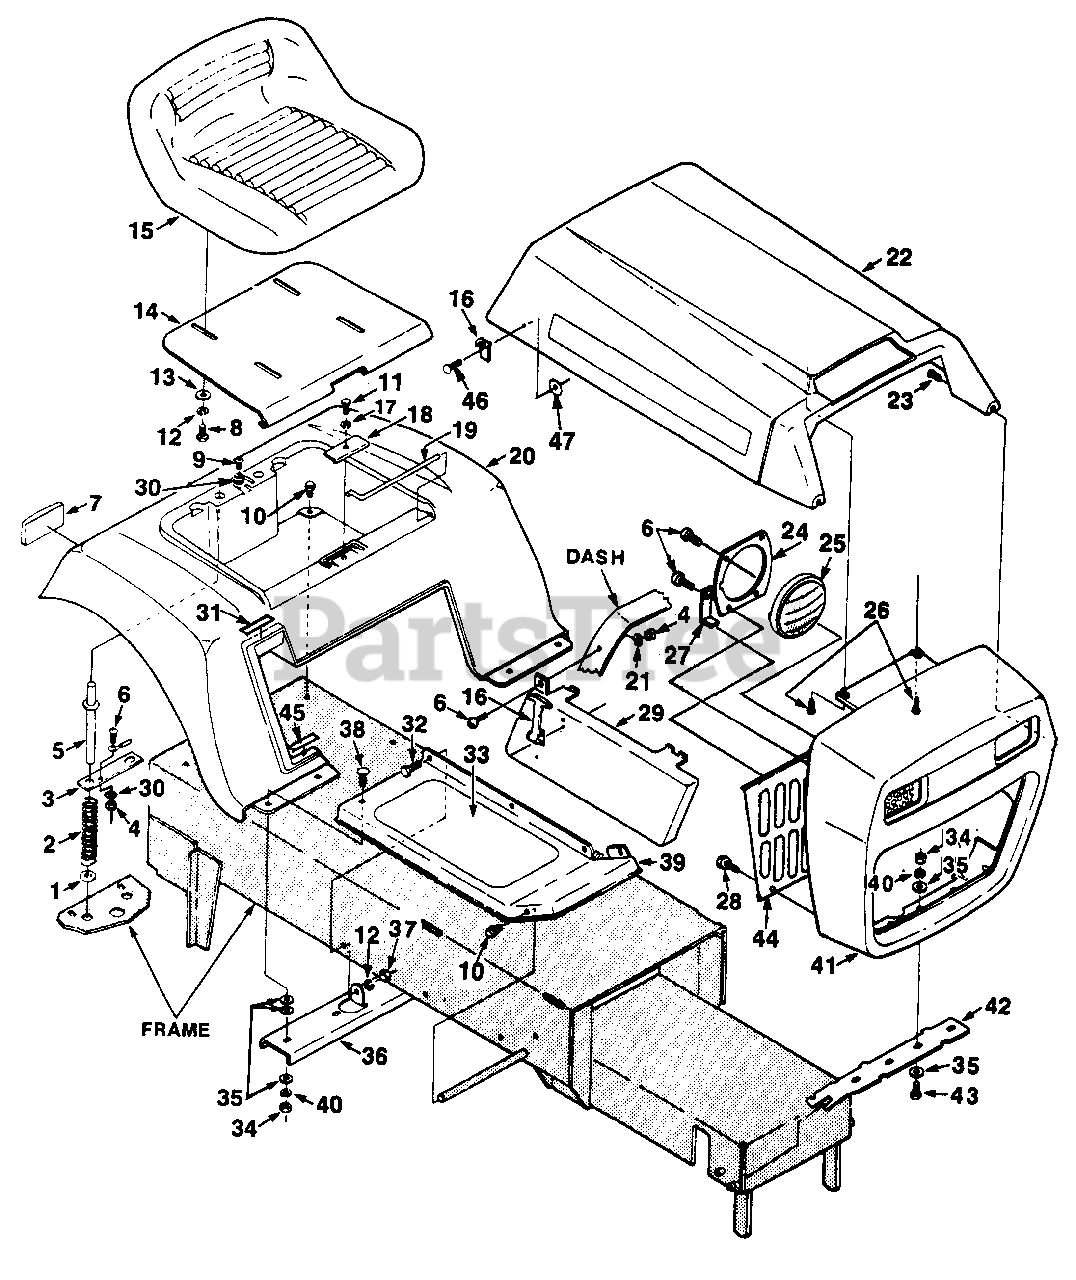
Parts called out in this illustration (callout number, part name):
1	WASHER- Insulation
2	SPRING- Compression
3	CONTACT- Interlock
4	NUT- Hex 10-24
5	PIN- Seat Support
6	SCREW- 10-24 x 3/8
7	REFLECTOR- Reflex
8	SCREW- Hex hd. 5/16-18 x 5/8
9	SCREW- #10 x 1/2
10	BOLT- 1/4-14 x .44
11	SCREW- Cap 1/4-20 x 3/4
12	WASHER- Lock 5/16
13	WASHER- 5/16
14	PAN- Seat
15	SEAT- Jacobsen
17	WASHER- Lock 1/4
18	BRACKET- Hitch
19	ROD- Hinge
23	SCREW- 1/4 x 14 x 1
24	RETAINER- Light
25	LIGHT- Head
26	SCREW- Tap hex 1/4-14 x 3/4
28	SCREW- 1/4-14 x 1/2
29	PANEL- Side R.H.
30	WASHER- Lock #10
31	DECAL- Hi-Lift Pos.
32	BOLT- Hex 5/16-18 x 1
33	PAD- Footboard
34	NUT- Hex 1/4-20
35	WASHER- Plain 1/4
36	BRACKET- Footboard
37	NUT- Hex 5/16-18
38	BOLT- 1/4-20 x 1
39	FOOTBOARD, R.H.
40	WASHER- Lock 1/4
42	HINGE- Grille
43	SCREW- 1/4-20 x 5/8
44	GRILLE SCREEN
45	DECAL- Lo-Lift Pos.
46	RIVET- Plain
47	WASHER- Flat
